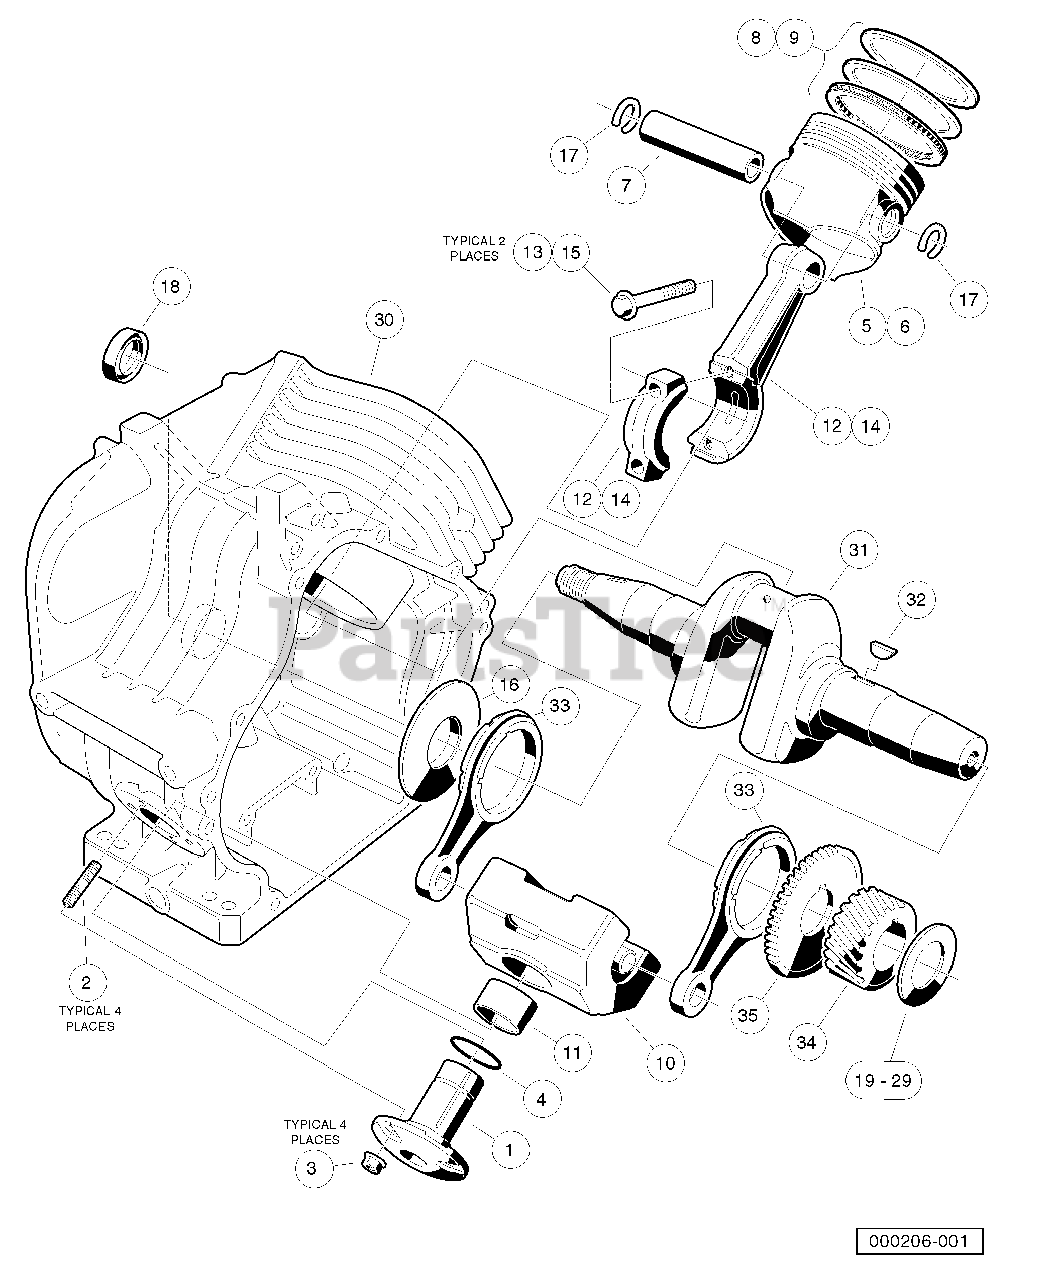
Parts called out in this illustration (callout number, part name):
1	Shaft, Guide, Counterbalance
2	Stud, 6x14
5	Piston, Standard
6	Piston, 0.50 mm Oversize
7	Pin, Piston
8	Ring Set, Standard Piston
9	Ring Set, Piston, 0.50 mm Oversize
10	Weight
11	Bearing, Plain
12	Asm, Con. Rod Std
14	Rod Assembly Connnecting Rod 0.5mm
19	Shim, Crankshaft, 1.18mm
20	Shim, Crankshaft, 1.25mm
21	Shim, Crankshaft, 1.32mm
22	Shim, Crankshaft, 1.39mm
23	Shim, Crankshaft, 1.46mm
24	Shim, Crankshaft, 1.53mm
25	Shim, Crankshaft, 1.60mm
26	Shim, Crankshaft, 1.67mm
27	Shim, Crankshaft, 1.74mm
28	Shim, Crankshaft, 1.11mm
29	Shim, Crankshaft, 1.81mm
30	Crankcase Complete, FE350
31	Crankshaft, FE350 Left-Hand, 22-Tooth
34	Gear, Helical
35	Gear, Spur
